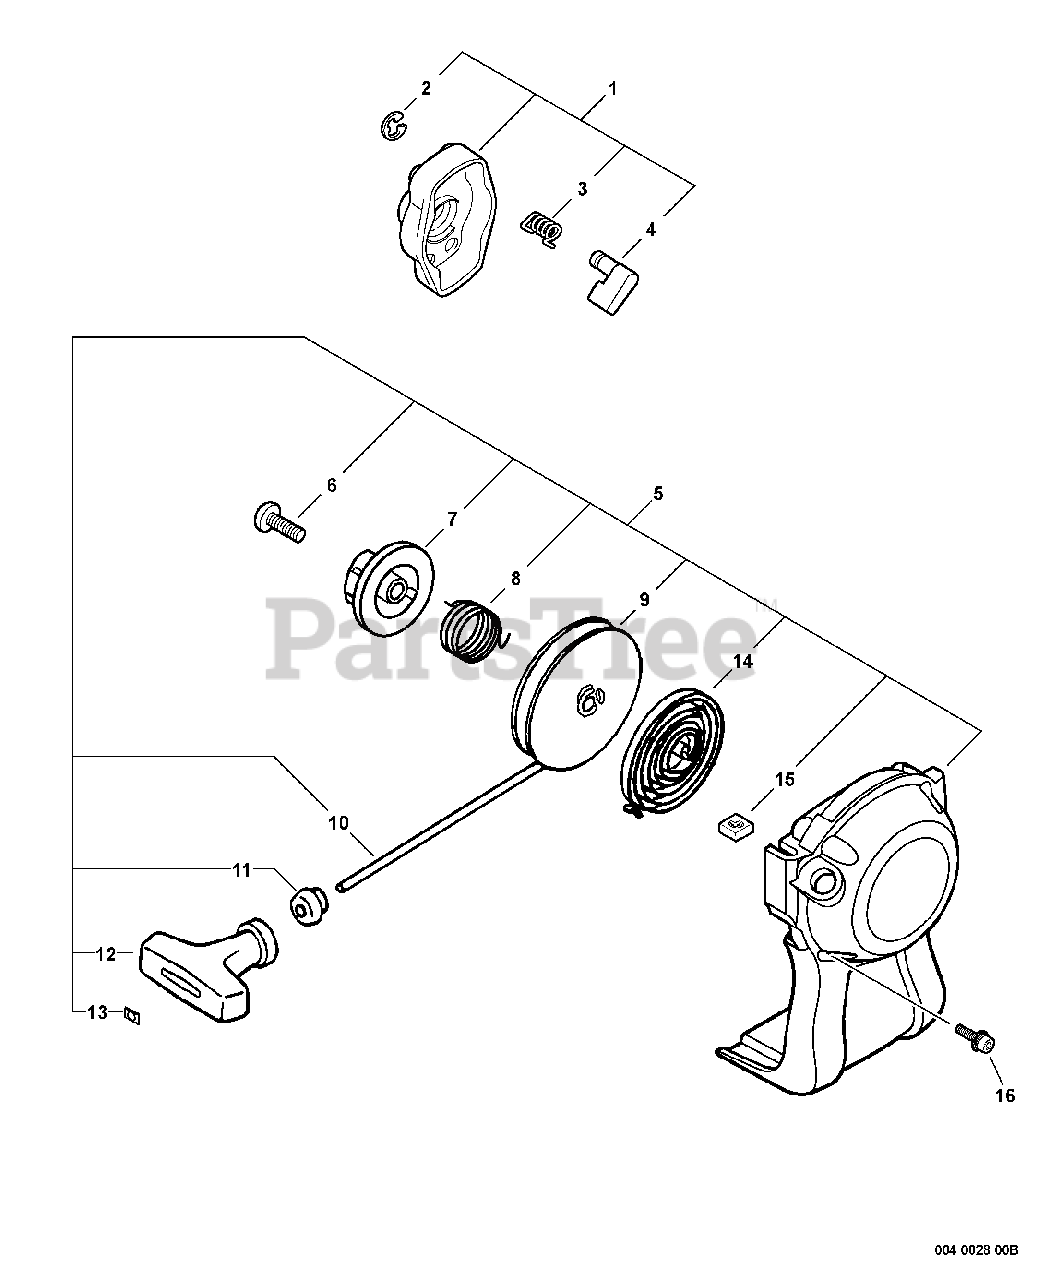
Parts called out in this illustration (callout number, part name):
1	STARTER PAWL ASSY
2	RING, RETAINING - 4
3	SPRING, RETURN
4	PAWL, STARTER
5	STARTER ASSY
6	SCREW
7	PLATE, CAM
8	SPRING, DAMPER
9	REEL, ROPE
10	ROPE, STARTER - 3X700
11	GUIDE, ROPE
12	GRIP, STARTER
13	RETAINER, ROPE
14	SPRING, REWIND
15	NUT - 5 -- SQUARE
16	SCREW - 4X16
